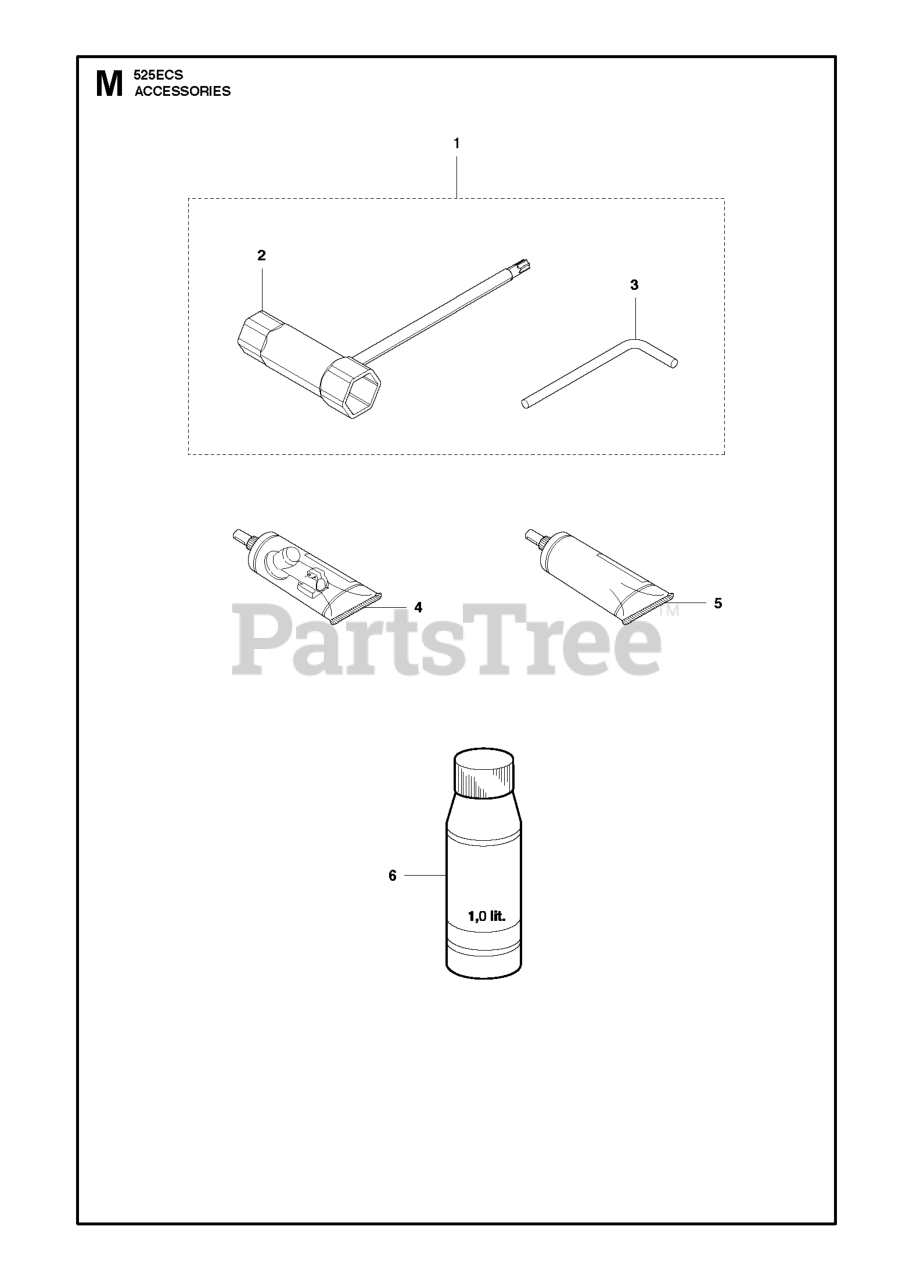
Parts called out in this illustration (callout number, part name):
4	DRIVE SHAFT GREASE (200 G)
5	BEVEL GEAR GREASE
6	Air Filter Oil 1l.
